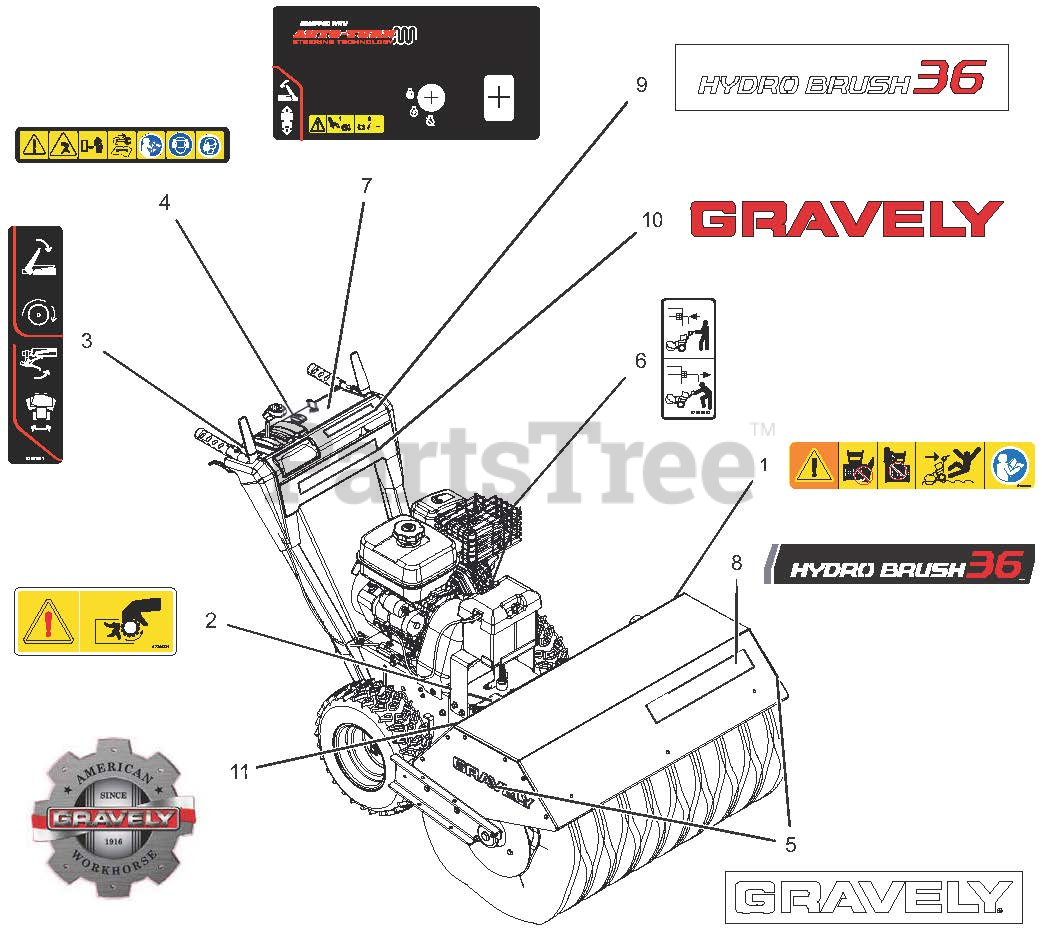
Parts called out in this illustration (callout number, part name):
1	DECAL, DANGER -POWER BRUSH-CE
2	DECAL, PTO WARNING
3	DECAL,CONTROL,BRUSH,RH
4	DECAL, SAFETY, DASH, BRUSH
5	DECAL, 13.5" GRAVELY LOGO
6	DECAL, HYDRO BRUSH BYPASS
7	DECAL,CONTROL-12V HYDRO BRUSH
8	DECAL,HYDRO BRUSH 36,GRAVELY
9	DECAL,HYDRO BRUSH 36,GRAVELY
10	DECAL,GRAVELY,RED,13"
11	DECAL, GRAVELY HERITAGE-LARGE
